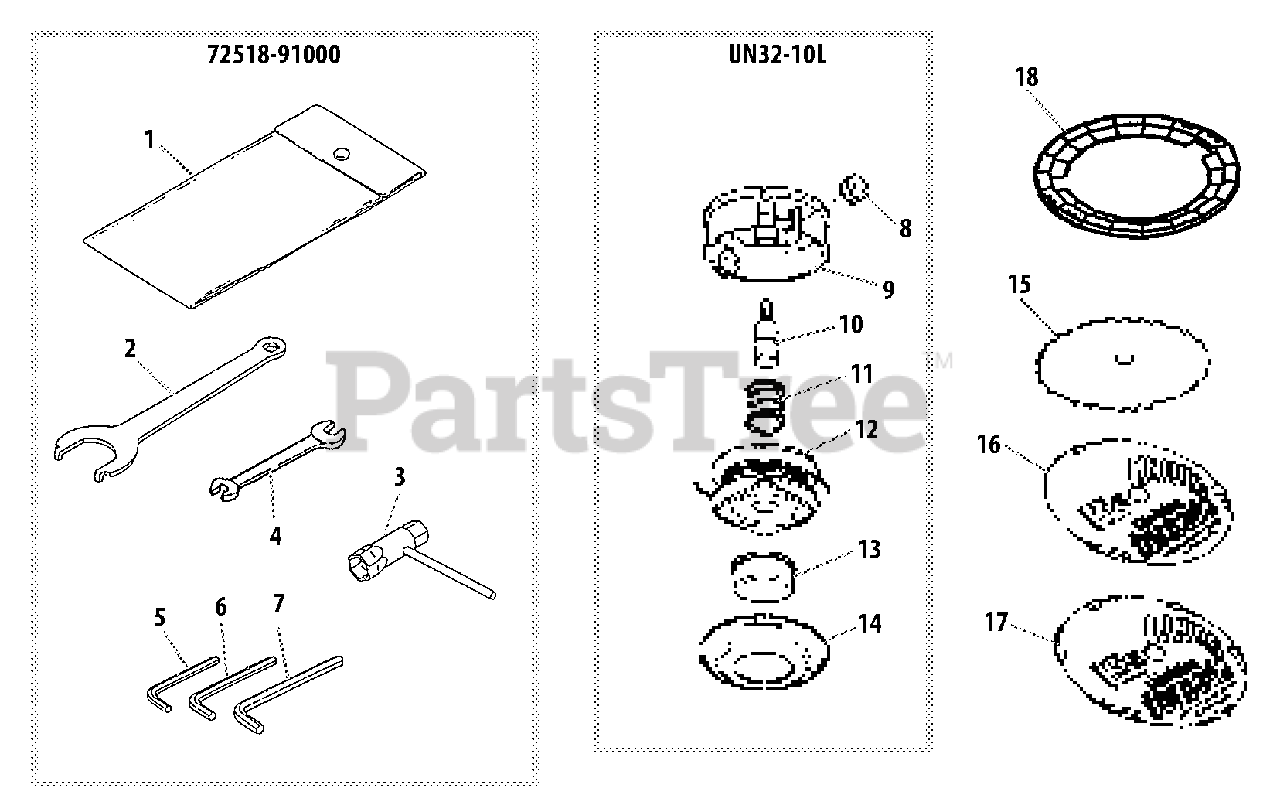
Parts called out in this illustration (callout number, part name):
1	BAG, TOOL
2	SPANNER
3	T-WRENCH
4	SPANNER - 8X10mm
5	HEX KEY - 3mm
6	HEX KEY - 4mm
7	HEX KEY - 6mm
10	SHAFT BOLT 10MM LH
15	BLADE - 30 TOOTH -- 9" (22cm)
16	BLADE - 6 TOOTH -- 9" (22cm)
17	BLADE - 12 TOOTH -- 9" (22cm)
18	COVER, BLADE
72518-91000	TOOL KIT
UN32-10L	TRIMMER HEAD ASSY
